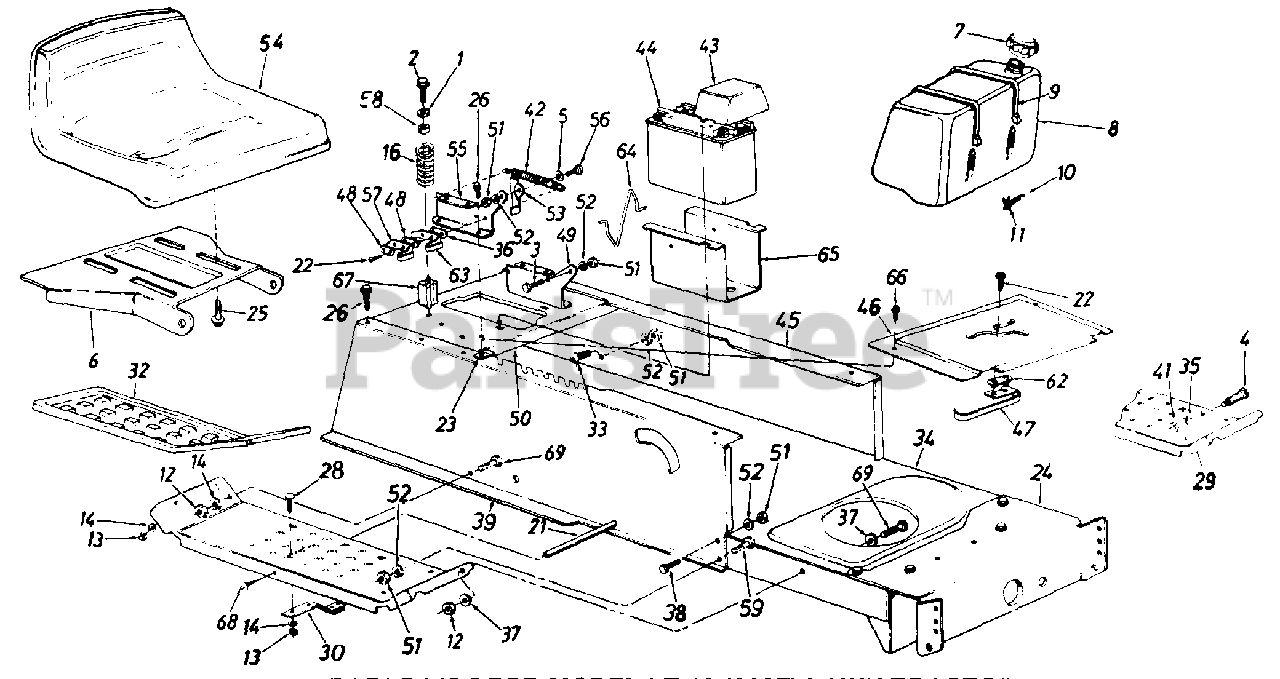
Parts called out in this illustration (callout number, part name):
1	Fl-Wash. .344" I.D. x .875"
2	Hex Wash. Hd. Tap Scr. 5/16-18 x 3.25" Lg.
3	Shld. Bolt .437" Dia. x .162"
4	Shld. Bolt .50" Dia. x .84"
5	Spr. Wash. .445" I.D. x .75
6	Seat Pivot Bracket
7	Fuel Cap
8	Fuel Tank
9	Tie Strap
10	Fuel Line
12	Hex Nut 1/4-28 Thd.
13	Hex Nut 1/4-20 Thd.
14	L-Wash. 1/4" I.D.
16	Compression Spring
21	Running Board Rod
22	Hex Wash. Hd. AB-Tap Scr. #8 x .50" Lg.
23	Speed Nut #10Z
24	Front Pivot Brkt.
25	Hex Tap Scr. 3/8-16 x .75"
26	Hex Wash. Hd. AB-Tap Scr. 5/16 x .75" Lg.
28	Carriage Bolt 1/4-20 x .62"
29	Running Board (R.H. & L.H.)
30	Blade Brake Ass'y.
32	Rubber Foot Pad - L.H.
33	Truss Mach. Scr. 5/16-18 x .75" Lg.
34	Lower Frame
35	L-Wash. 3/8" I.D.
36	Insulator Boss Plate
37	Fl-Wash. .25" I.D. x .625" O.D.
38	Hex Bolt 5/16-18 x .75" Lg.
39	Upper Frame - R.H.
41	Hex Nut 3/8-16 Thd.
42	Extension Spring 5.31" Lg.
43	Battery Cover
44	12-V Battery
45	Upper Frame - L.H.
47	Reverse Safety Switch
48	Insulator Plate
52	L-Wash. 5/16" I.D.
53	Seat Lift Brkt.
54	Seat 10-5/8" High
56	Shld. Bolt .437" Dia. x .268"
57	Spring Switch
59	Hex Wash. TT-Tap Scr. 5/16-18 x 7/8" Lg.
62	Insulator Nut Plate
63	Safety Switch (Seat)
64	Battery Tray Clip
65	Battery Tray
66	Truss Mach. B-Tap Scr. #10 x .5" Lg.
67	Spring Spacer
68	Pan Hd.Cutting Scr. 5/16-18 x .75" Lg.
69	Hex Bolt 1/4-28 x .75" Lg.
